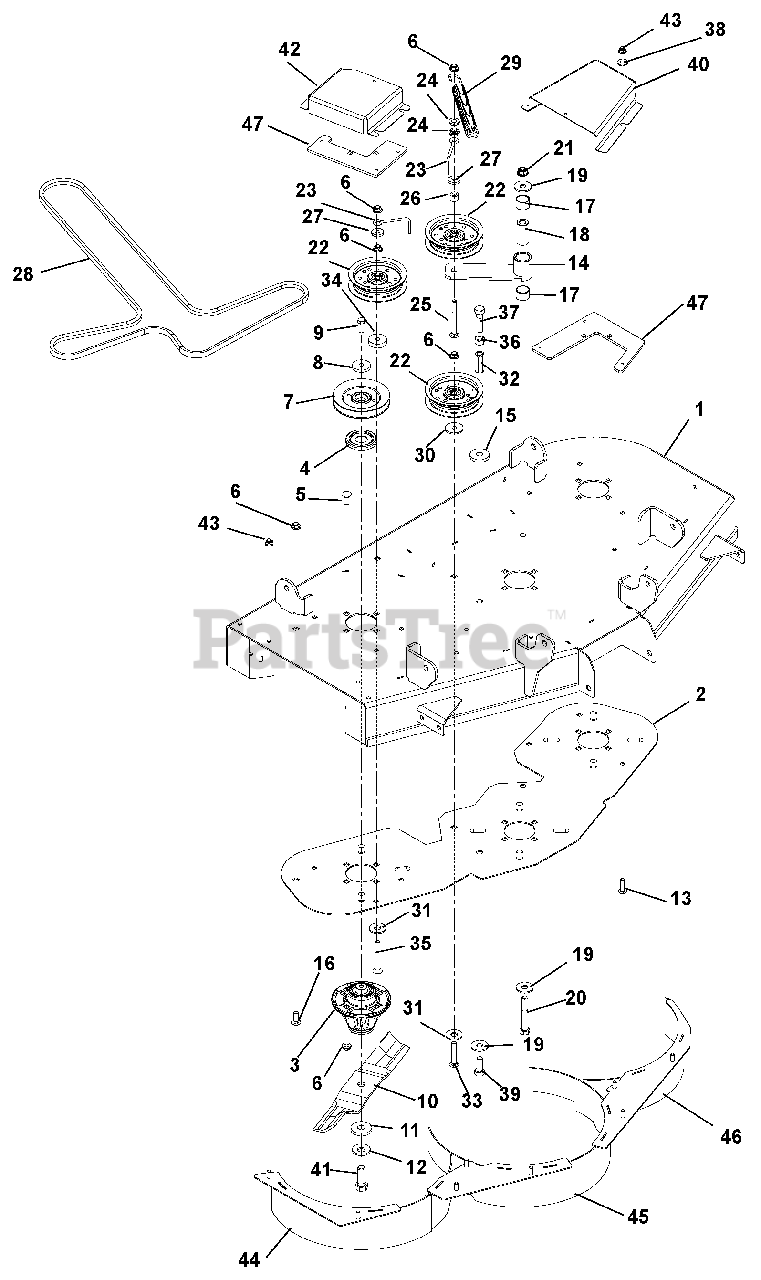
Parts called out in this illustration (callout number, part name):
1	XL – Deck Kit CE
2	Doubler Plate, 42" Deck
3	Spindle Assembly
4	Dust Cap
5	Bolt, Round Head Square Neck .38-16 x 1.25 Grade 5
6	Nut, .38-16 Nyloc Flange
7	Pulley, Spindle
8	Washer, Flat Steel .406 x 1.50 x .245
9	Bolt, Hex .38-16 x 1.00 EP30
10	Blade, Mulch 14.50"
11	Washer, Flat .640 x 1.75 x .250
12	Washer, Bellville .63 x 1.625 x .14
13	Bolt, Serrated Hex Flange Washer Head .312-18 x .50
14	Idler Arm
15	Washer, Flat Steel .515 x 1.625 x .250 YZ
16	Bolt, Round Head Square Neck .38-16 x 1.00 Grade 5
17	Bearing, 1.00 x 1.12 x .75
18	Bushing, Spacer .505/.500 x .999/.996 x 2.05/2.03 Promaster
19	Washer, Flat Steel .511 x 1.441 x .125
20	Bolt, Hex .50-13 x 3.50 Grade 5
21	Nut .50-13 Nyloc Flange
22	Assembly, Idler 4"
23	Belt Finger
24	Bushing, Flange .406 x .88 x .270 x .140
25	Bolt, Round Head Square Neck .38-16 x 3.50 Grade 5
26	Bushing, Sleeve .391 x .688 x .52
27	Washer, Flat Steel .406 x 1.00 x .188
28	Belt, HA 127.12 Wrapped
29	Extension Spring
30	Washer, Flat Steel .39 x 1.5 x .125
31	Plate, Idler Mount Reinforcement
32	Nut, Coupling .50-13 x 1.75
33	Bolt, Round Head Square Neck .38-16 x 2.25 Grade 5
34	Spacer, .39 x 1.50 x .380
35	Bolt, Round Head Square Neck .38-16 x 3.50 Grade 5
36	Nut, Hex .50-13
37	Bolt, Hex .50-13 x 2.00 Grade 5
38	Washer, Flat Steel .38 x .875 x .083
39	Bolt, Hex .50-13 x 1.25 Grade 5
40	Belt Cover, Left
41	Bolt, Hex .62-18 x 1.75 Grade 8
42	Belt Cover, Right
43	Nut, .31-18 Nyloc Flange
44	Weldment, 42 Baffle Right Hand
45	Weldment, 42 Mulch Baffle (CTR)
46	Weldment, 42 Mulch Baffle Left Hand
47	Bracket, Belt Cover Mount - LHS
